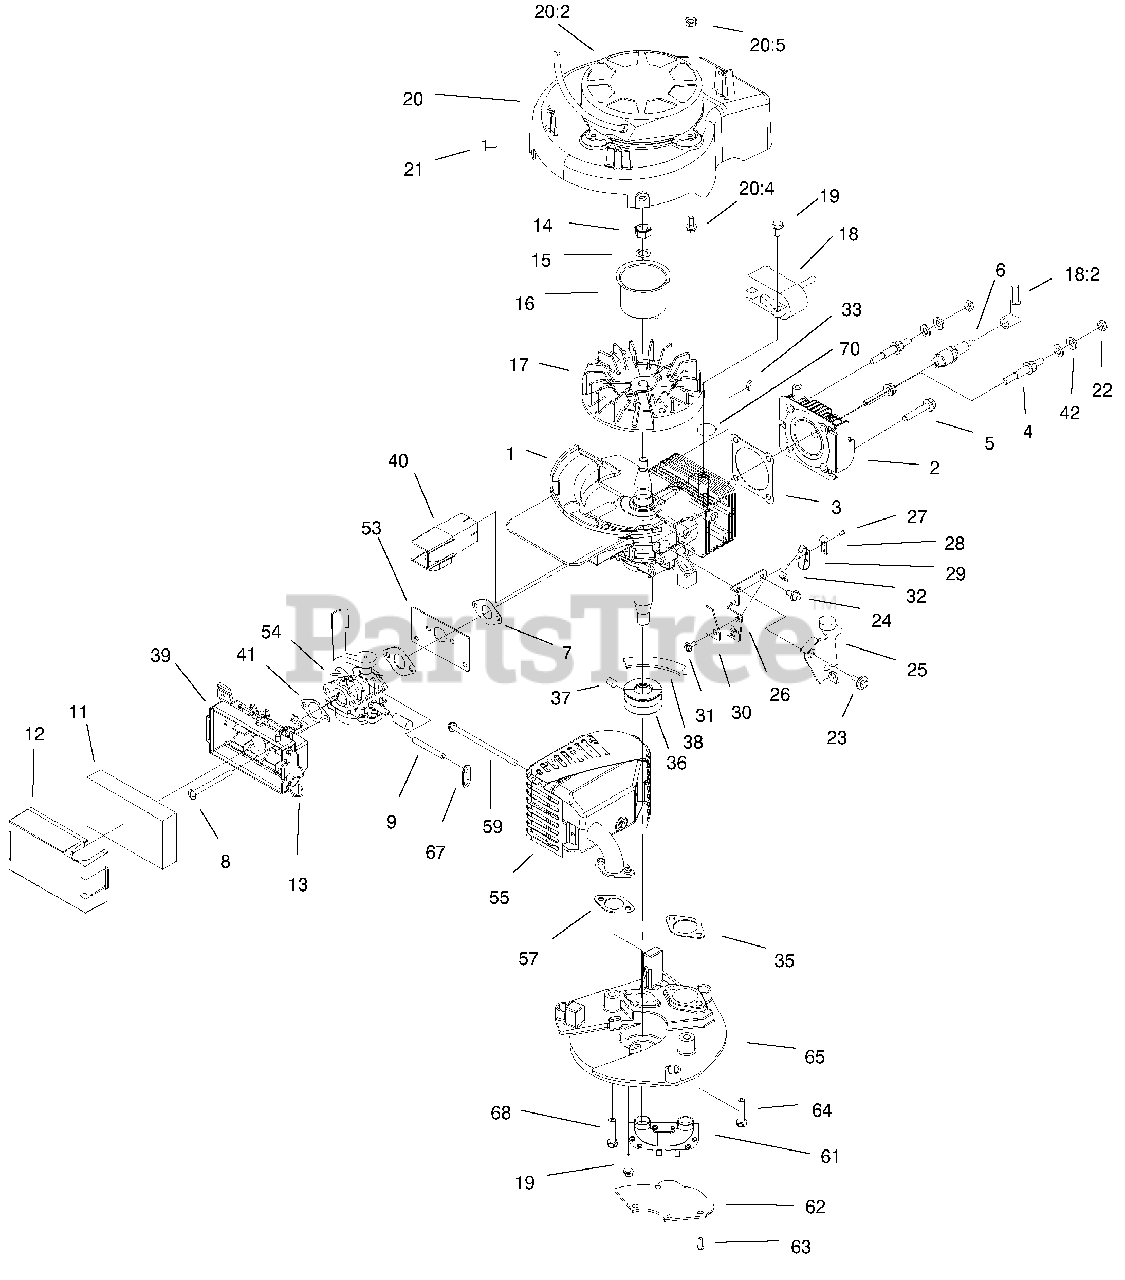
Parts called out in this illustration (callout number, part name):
1	SHORT BLOCK ASM
2	HEAD-CYLINDER
3	GASKET-HEAD
5	SCREW-HWH
6	SPARK PLUG
7	GASKET-INTAKE
9	HOSE-PRIMER
11	FILTER-AIR
12	COVER-FILTER, AIR
13	RETAINER-COVER, FILTER
15	WASHER-LOCK
16	CUP-STARTER
17	FLYWHEEL
18	MODULE-IGNITION
18:2	LEAD-TENSION, HIGH
20	SHROUD-RECOIL
20:2	RECOIL ASM
20:4	SCREW-HWH
20:5	NUT-LOCK
21	SCREW-HH
23	SCREW-SHOULDER
24	SCREW-HWH
25	PLATE-BRAKE
26	PLATE-BRAKE
27	RIVET-PLASTIC
28	STRAP-INSULATION
29	STRAP-GROUND
30	STOP-STRAP, GROUND
32	LEAD WIRE-SWITCH, BRAKE
35	GASKET-EXHAUST
37	SCREW-SET
38	V-BELT E
39	AIR BASE ASM
40	TUNNEL-INLET
41	GASKET-FILTER
42	WASHER-BELLEVILLE
53	SHIELD-CARB
54	CARBURETOR ASM
55	MUFFLER AND GUARD
59	BOLT-CONSOLE
61	PIPE-TRANSFER
62	COVER-MUFFLER
63	SCREW-HH
64	SCREW-HH
65	PLATE-MOUNTING
67	HOSE-RETAINER
70	STRAP-TIE
